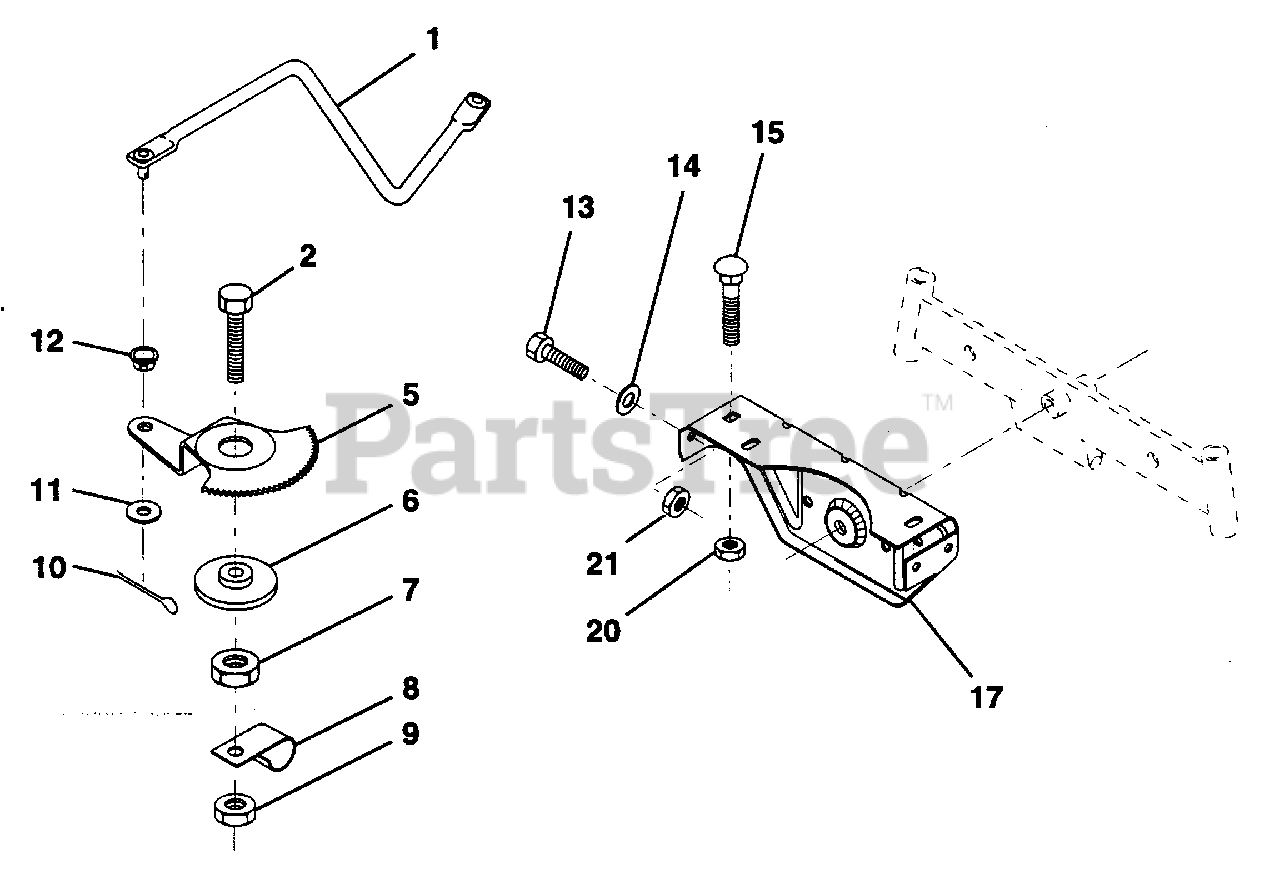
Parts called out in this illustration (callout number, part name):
2	Bolt, Fin Hex 1/2-13 x 1-3/4
7	Nut, Heavy Hex Top Lock 1/2-13 UNC
8	Clip, Insulated
9	Nut, Crownlock 3/8-16
10	Pin, Cotter 1/8 x 3/4
11	Washer, 13/32 x 13/16 x 16 Ga.
13	Bolt, Hex Hd. 5/16-18 UNC x 3/4
14	Washer 11/32 x 7/8 x 16 Ga.
15	Bolt, Carriage 3/8-16 UNC x 3/4
17	Support, Front Axle
20	Nut, Crownlock 3/8-16
21	Nut, Crownlock 5/16-18
